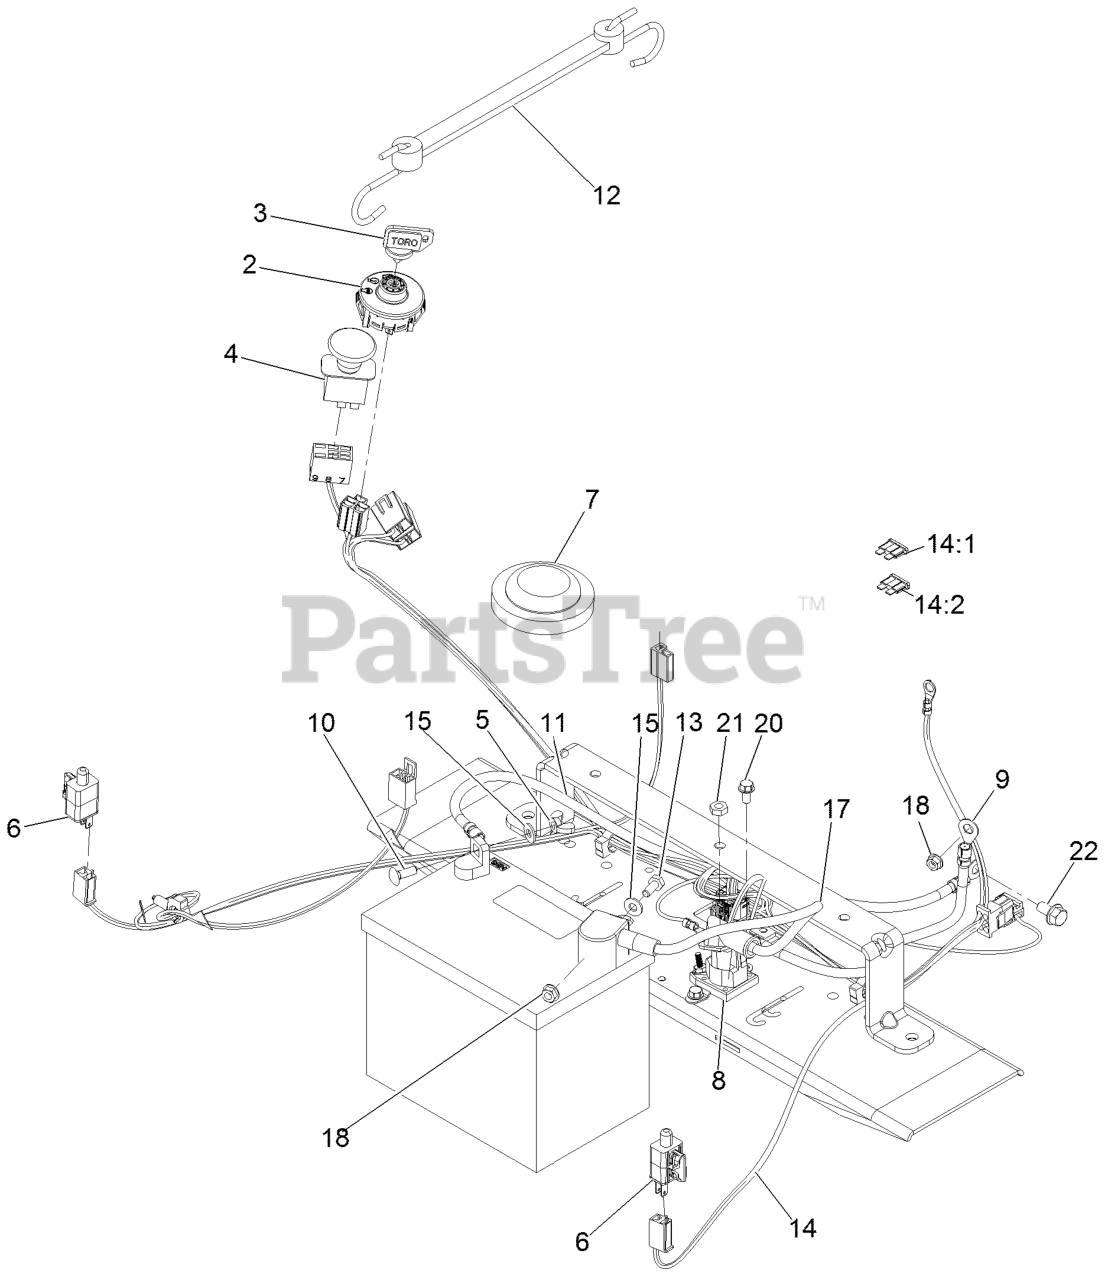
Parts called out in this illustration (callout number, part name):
3	KEY-IGNITION
4	SWITCH-PTO
5	NUT-WING
7	SWITCH-SEAT
8	SOLENOID
9	CABLE-BATTERY, RED
10	BOLT-CARR
11	CABLE-BATTERY, BLACK
12	HOLDDOWN-BATTERY
13	SCREW-HH
14:1	FUSE-BLADE, 30 AMP
14:2	FUSE-BLADE, 25 AMP
15	WASHER-FLAT
17	CABLE-BATTERY, RED
20	SCREW-HWH
21	NUT-JAM
22	SCREW-HHF
